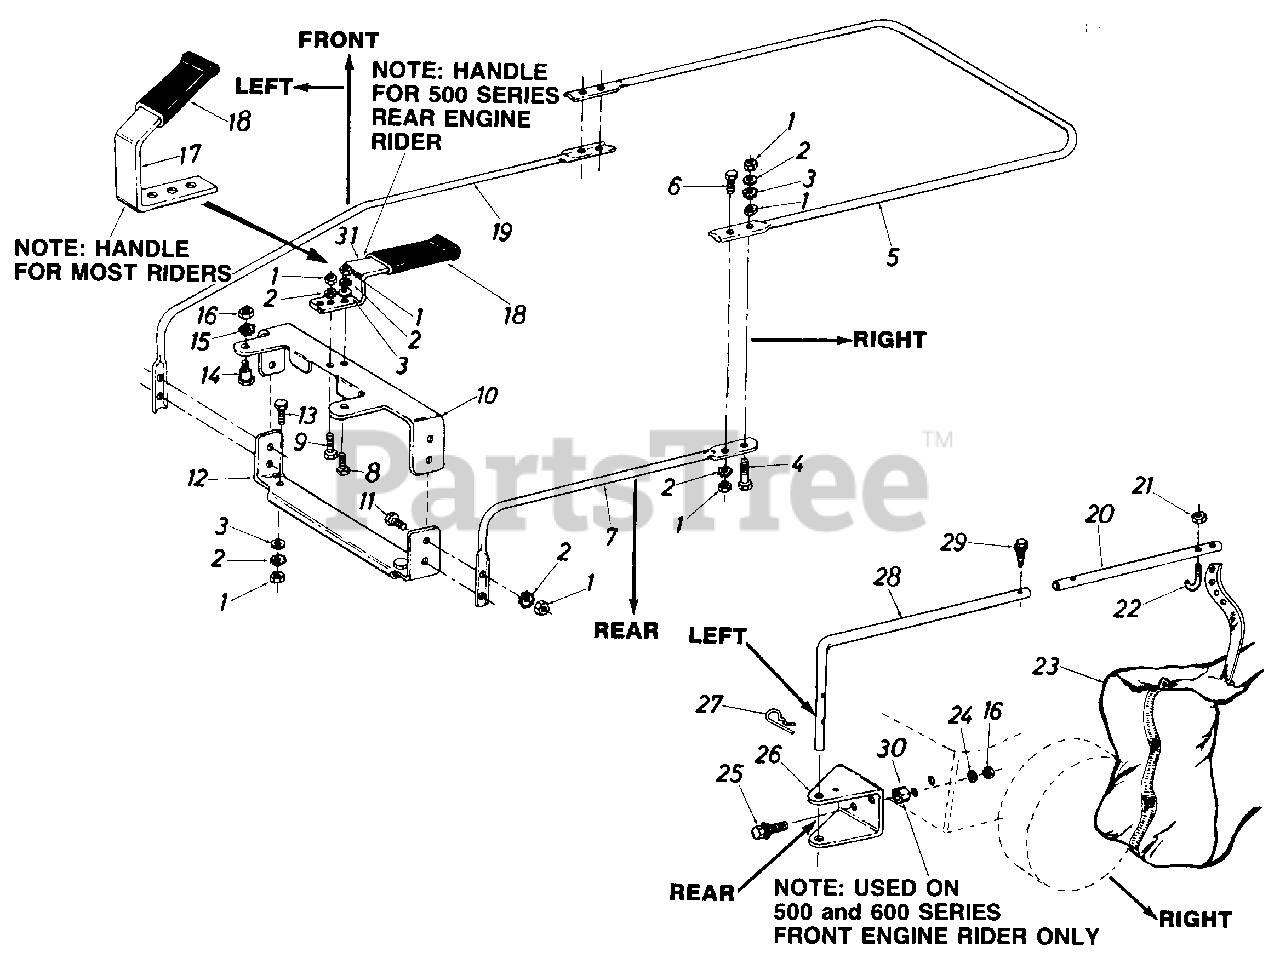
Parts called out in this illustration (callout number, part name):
1	Hex Nut 1/4-20 Thd.*
2	Ext. L-Wash. 1/4" I.D.
3	Fl-Wash. .281" I.D. x .5" O.D.
4	Hex Bolt 1/4-20 x 1.5" Lg.
5	Upper Frame Half
6	Hex Bolt 1/4-20 x 1" Lg.
7	Lower Frame Tubing
8	Hex Bolt 1/4-20 x .62" Lg.
9	Hex Bolt 1/4-20 x .85" Lg.
10	Upper Opening Support
11	Hex Bolt 1/4-20 x 1" Lg.
12	Lower Opening Support
13	Hex Bolt 1/4-20 x .50" Lg.*
14	Shld. Bolt .437 Dia. x .350
15	Ext. L-Wash. 5/16" I.D.
16	Hex Nut 5/16-18 Thd.
19	Lower Frame Arm
23	1 Grass Catcher Bag
24	L-Wash. 5/16" I.D.*
25	Hex Sems Bolt 5/16-18 x .75" Lg.
26	Hitch Bracket
27	Internal Cotter Pin 518" Dia.
28	Lower Holding Arm
29	Hex Self-Tap .50" Lg.
30	Spacer
31	Handle
